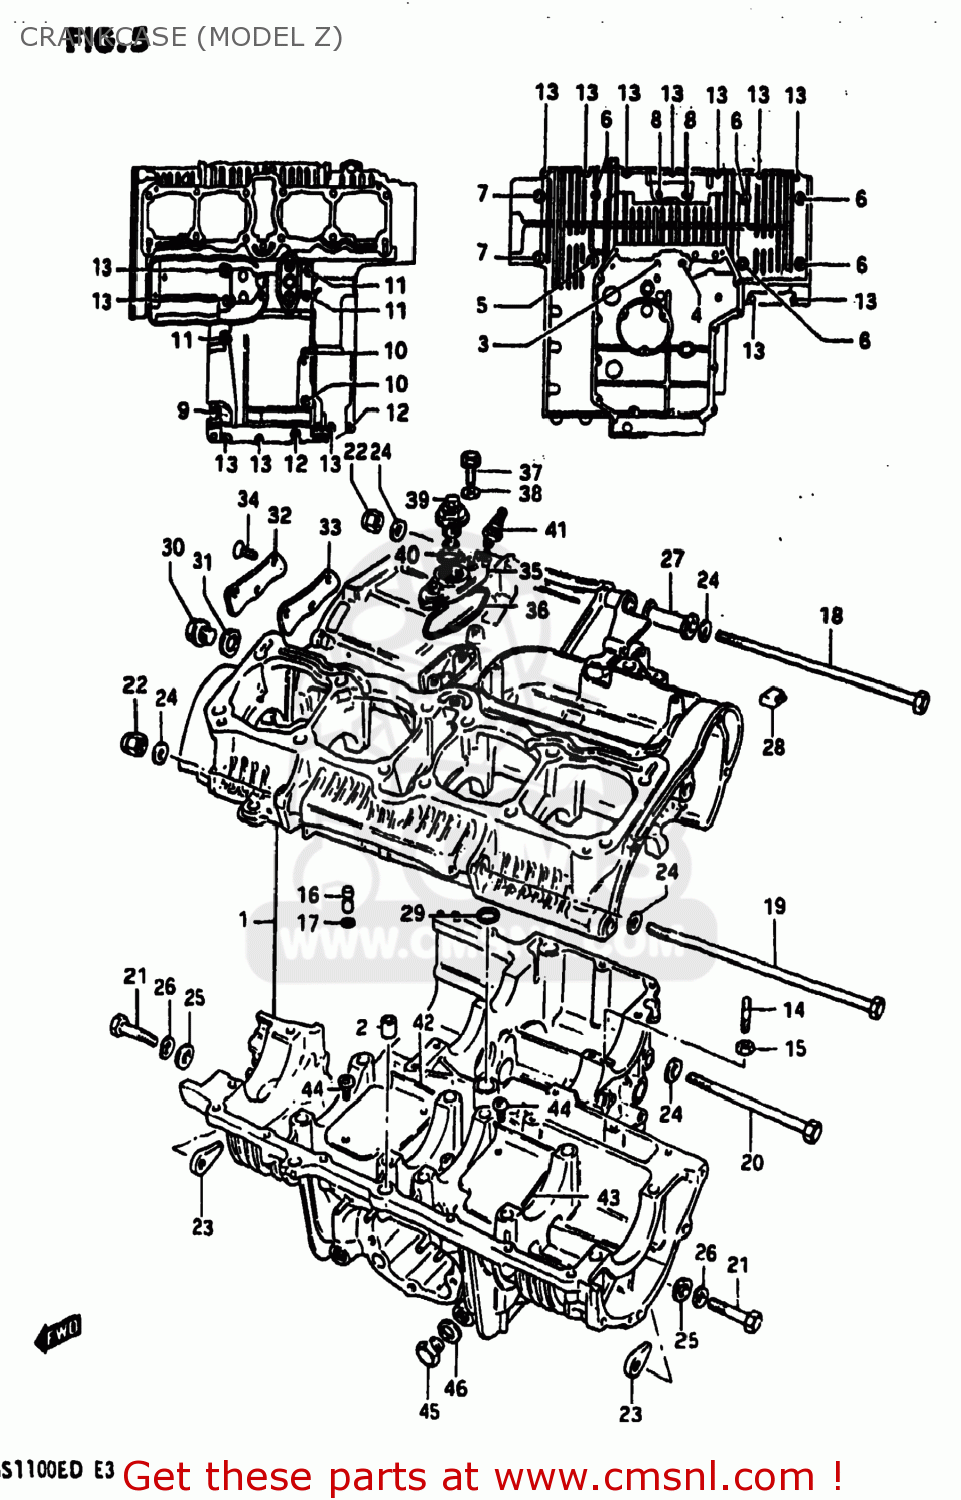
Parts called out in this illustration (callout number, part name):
1	CRANKCASE SET
2	PIN
3	BOLT 8X155
4	BOLT
5	BOLT
6	BOLT 8X90
7	BOLT 8X65
8	BOLT
9	BOLT
10	BOLT
11	BOLT (6X75)
12	BOLT
13	BOLT
14	STUD BOLT
15	NUT
16	UNION
17	O RING(D:1.05,ID:3.1)
18	BOLT 10X230
19	BOLT 10X250
20	BOLT(10X165)
21	BOLT 10X60
22	NUT
23	NUT
24	WASHER
25	WASHER(10.5X20X3.2)
26	LOCK WASHER
27	SPACER
28	PAD,CYLINDER
29	O RING(D:3.2,ID:12.9)
30	PLUG (14X12)
31	GASKET(14X19.2X2) (NAS)
32	GASKET(14X19.2X2) (NAS)
33	GASKET,OIL GALLERY (MCA)
34	SCREW
35	HOUSING,OIL PRESSURE SWITCH
36	O RING,PRESSURE SWITCH HOUSING
37	BOLT
38	GASKET (NAS)
39	SWITCH ASSEMBLY
40	O RING(D:1.9,ID:18.8)
41	GAUGE ASSEMBLY,OIL TEMPERATURE
42	PLATE,OIL SEPARATOR
43	PLATE,OIL SEPARATOR
44	SCREW
45	PLUG
46	GASKET(14X19.2X2) (NAS)
